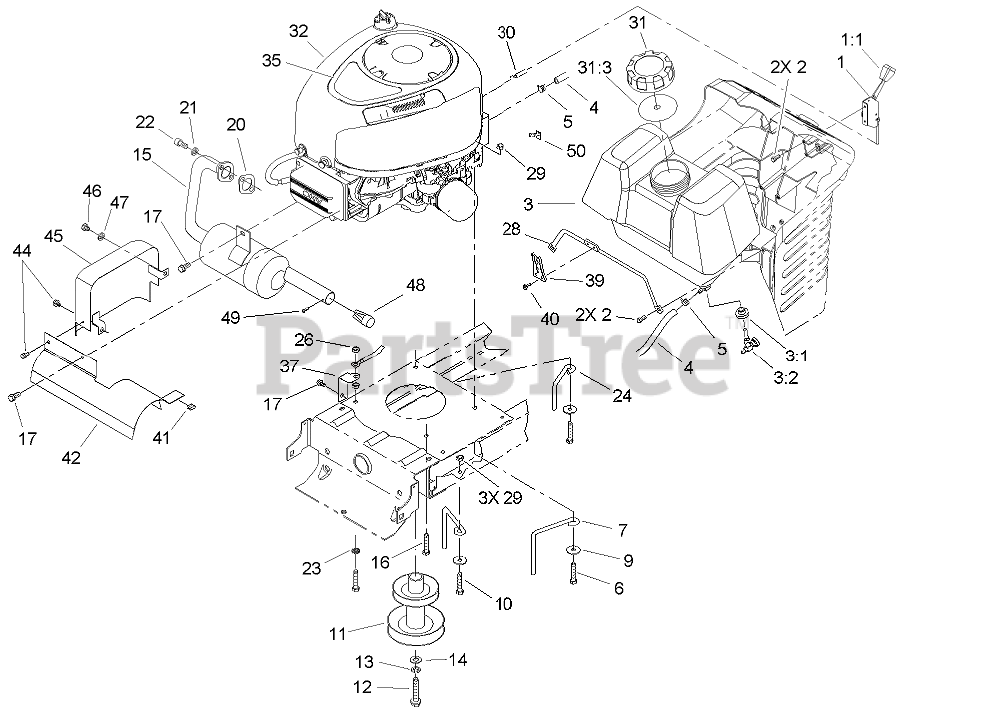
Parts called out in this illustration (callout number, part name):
1	THROTTLE CONTROL ASM
2	SCREW-SPECIAL
3	GAS TANK ASM
3:1	BUSHING
3:2	VALVE-FUEL
4	HOSE-FUEL
5	CLAMP-HOSE
6	SCREW-HH
7	GUIDE-BELT, ENGINE
9	WASHER-PIVOT
10	SCREW-HH
11	Pulley-Engine
12	SCREW-HH
13	WASHER-LOCK
14	WASHER-FLAT
15	MUFFLER
16	SCREW-HWH, TAPTITE
17	SCREW-HWH
20	GASKET-EXHAUST
21	WASHER-LOCK
22	SCREW-HSH
23	WASHER-LOCK
24	GUIDE-BELT, RH
26	NUT-KEPS
28	ROD-TANK, GAS
29	NUT-LOCK, NI
30	THROTTLE CABLE ASM
31	GAS CAP ASM
31:3	GASKET-CAP, GAS
35	DECAL-ENGINE
37	BRACKET-GROUND
39	LATCH-HOOD
40	SCREW-HWH
41	CLIP-TINNERMAN
42	SHIELD-MUFFLER
44	SCREW-HWHTF
45	HEAT SHIELD ASM
46	SCREW-HH
47	WASHER-LOCK
48	SCREEN-SILENCER, EXHAUST
49	SCREW-THD FORM, HWH
50	REDUCER-THROTTLE, RPM
